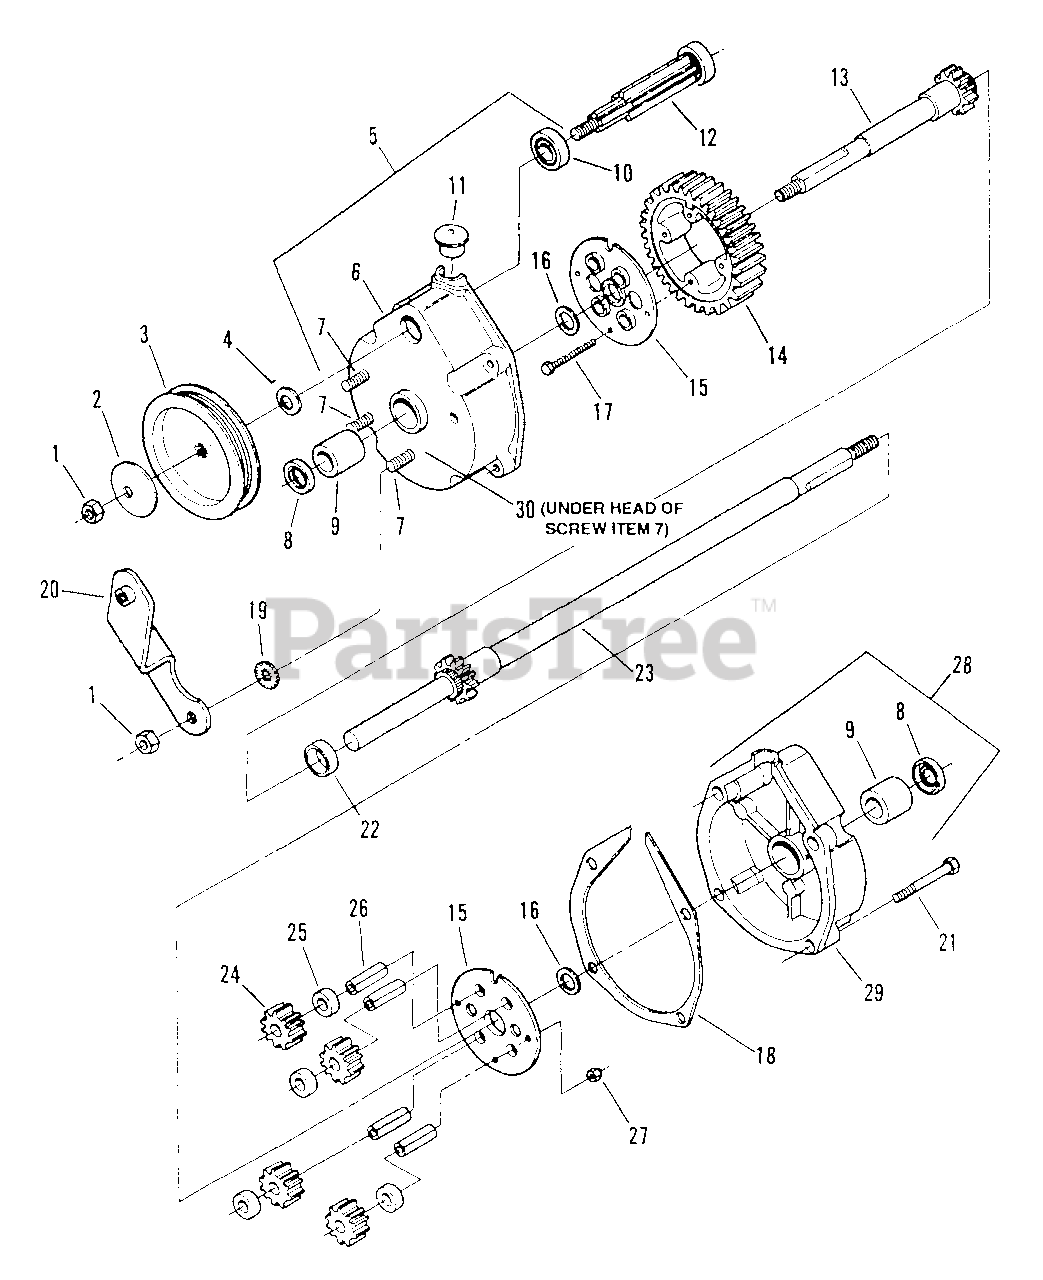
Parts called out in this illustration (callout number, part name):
1	NUT, 5/16-24 Hex Lock
2	WASHER, Spring
3	PULLEY, Poly-Vee Belt
4	WASHER, Spring
5	ASSEMBLY, Housing Right
6	HOUSING, Right Side
7	SCREW, 5/16-24 x 1-1/8" Rib Neck
8	SEAL, 5/8 I.D.
9	BEARING, Differential
10	BEARING, Ball
11	PLUG, Housing
12	GEAR, Input
13	AXLE, Short
14	GEAR, Differential (46 Tooth)
15	PLATE
16	WASHER, Thrust
17	SCREW, #10-32 x 1-1/2" Hex Head Cap
18	GASKET, Housing
19	WASHER, 5/16 Internal/External Tooth Lock
20	BRACKET, Differential
21	SCREW, 1/4-20 x 1-1/4" Self-Tapping
22	SPACER, Axle Gear
23	AXLE, Long
24	GEAR, Pinion (12 Tooth)
25	SPACER, Pinion Gear
26	SHAFT, Pinion
27	NUT, #10-32 Hex Lock
28	ASSEMBLY, Housing Left
29	HOUSING, Left Side
30	GASKET, 5/8 O.D.
